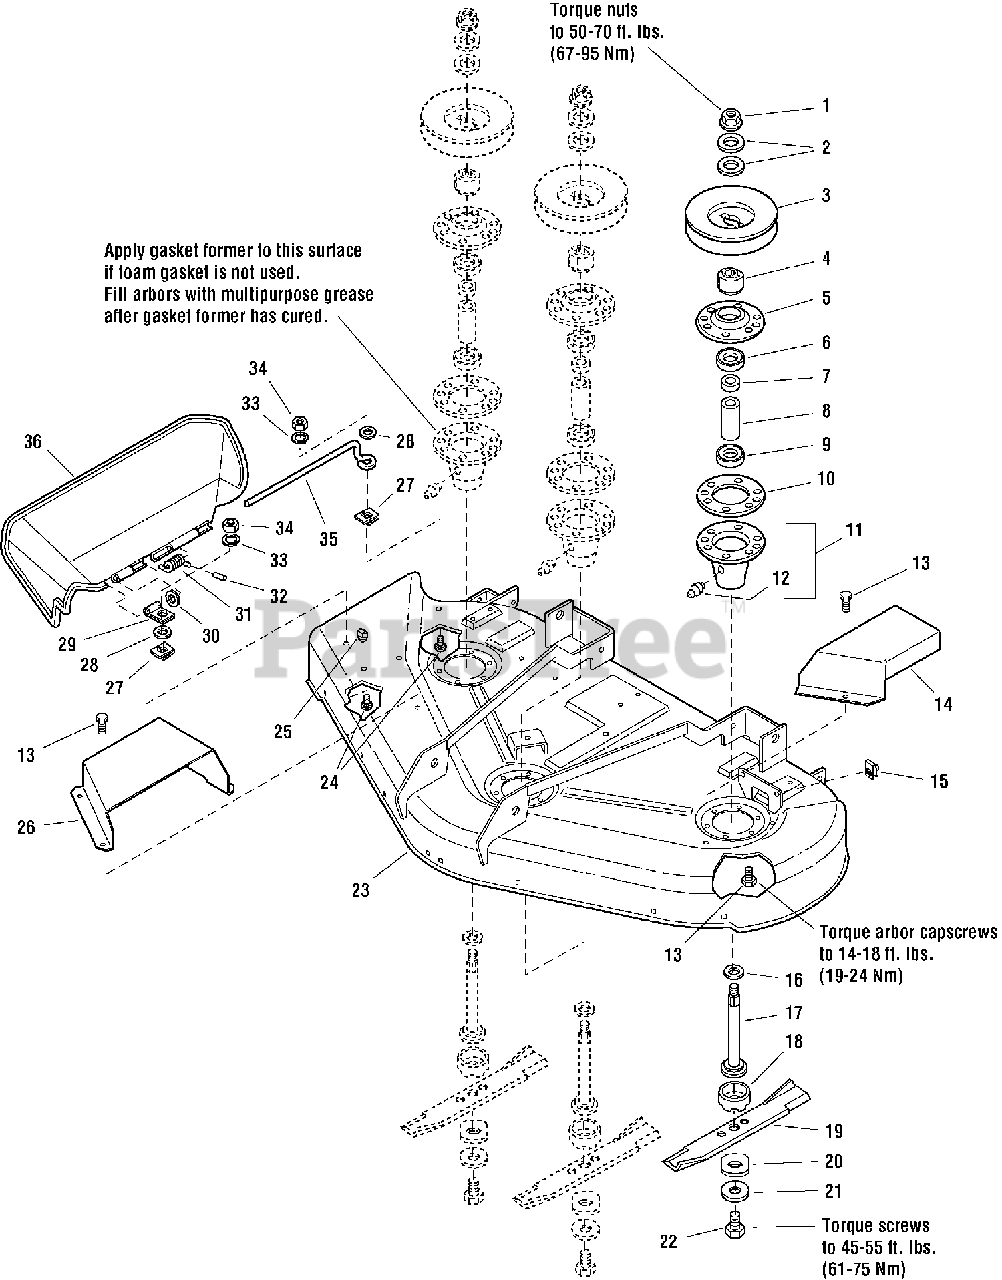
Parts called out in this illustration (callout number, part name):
1	NUT, HEX FLANGE, 9/16-18
2	WASHER, Bellville, 9/16
3	PULLEY
4	HUB
5	COVER, ARBOR HOUSING
6	BEARING, BALL, 3/4 X 1-3/4 X 5/8
7	SPACER, 21/32 X 3/4 X 5/8
8	SPACER, 11/16 X 5/32 X 2-11/16
9	BEARING, BALL, 11/16 X 1-9/16 X 15/32
10	SEAL, FOAM
11	ARBOR HOUSING ASSEMBLY (INCLUDES REF. NO. 12)
12	FITTING, GREASE
13	CAPSCREW, HEX HEAD TAPTITE, 5/16-18 X 3/4
14	COVER, ARBOR, LH
15	BODY CLIP, 5/16-18
16	WASHER, 9/16, BLACK
17	SHAFT, ARBOR
18	SHIELD, GRASS, LOWER
19	BLADE, MOWER, 16-1/8 (FOR 44" DECKS)
19	BLADE, MOWER, 18-1/8 (FOR 50" DECKS)
20	WASHER, HEX, 11/16 X 2
21	WASHER, SPRING, 15/32, BLACK
22	CAPSCREW, HEX HEAD, 7/16-14 X 1-1/4
23	DECK SHELL W/DECALS, 44" MOWER (includes decals)
23	DECK SHELL W/DECALS, 50" MOWER (includes decals)
24	CARRIAGE BOLT, 1/4-20 X 7/8
25	PLUG, HOLE
26	COVER, ARBOR, RH
27	NUT, PUSH
28	WASHER, 1/4, BLACK
29	CLAMP
30	WASHER, 5/16, BLACK
31	SPRING
32	VINYL CAP
33	WASHER, LOCK, 1/4
34	NUT, HEX, 1/4-20
35	ROD, DEFLECTOR
36	DEFLECTOR, PLASTIC
